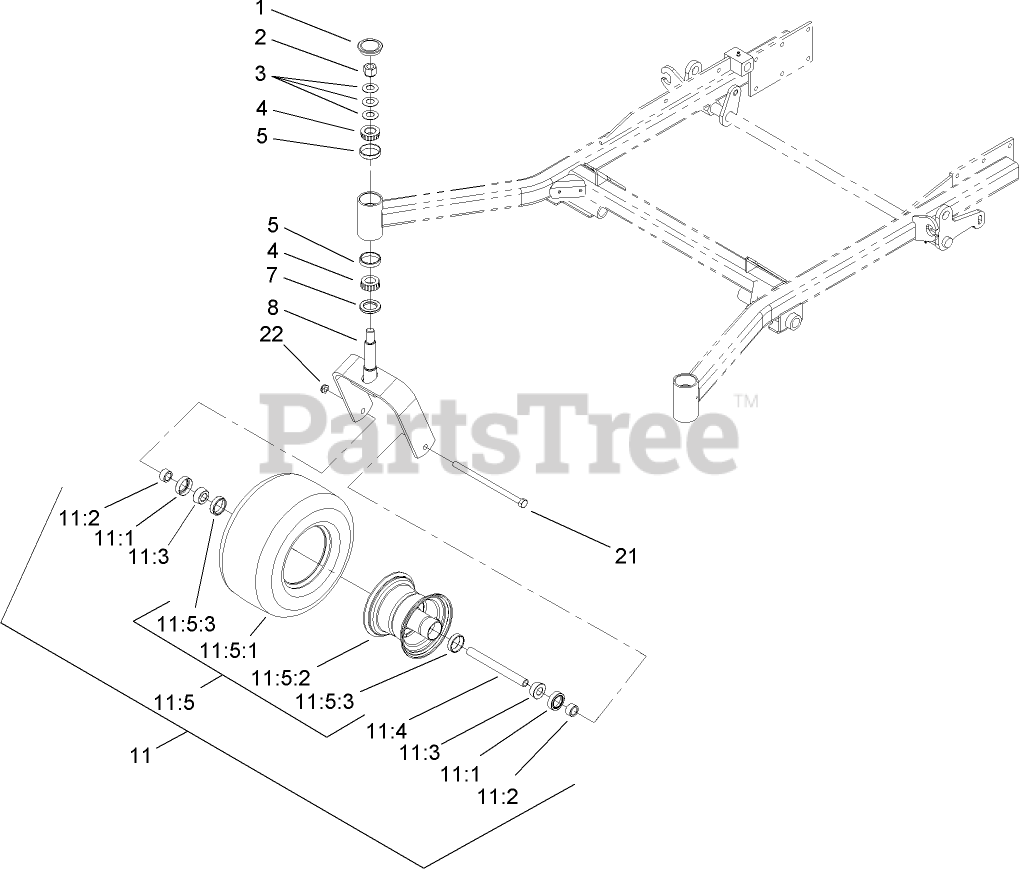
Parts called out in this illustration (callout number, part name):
1	CAP-GREASE
2	NUT-LOCK, NI
3	WASHER-BELLVILLE
4	BEARING-CONE, TAPERED
5	BEARING-CUP, TAPERED
7	SEAL-GREASE
8	CASTER-FORK
11	CASTER WHEEL ASM
11:1	SEAL-BEARING
11:2	SPACER-BEARING
11:3	BEARING-CONE, TAPER
11:4	SPACER-CASTER, FRONT
11:5	Wheel and Tire ASM
11:5:3	BEARING-CUP
21	Screw-HH
22	NUT-LOCK, NI
